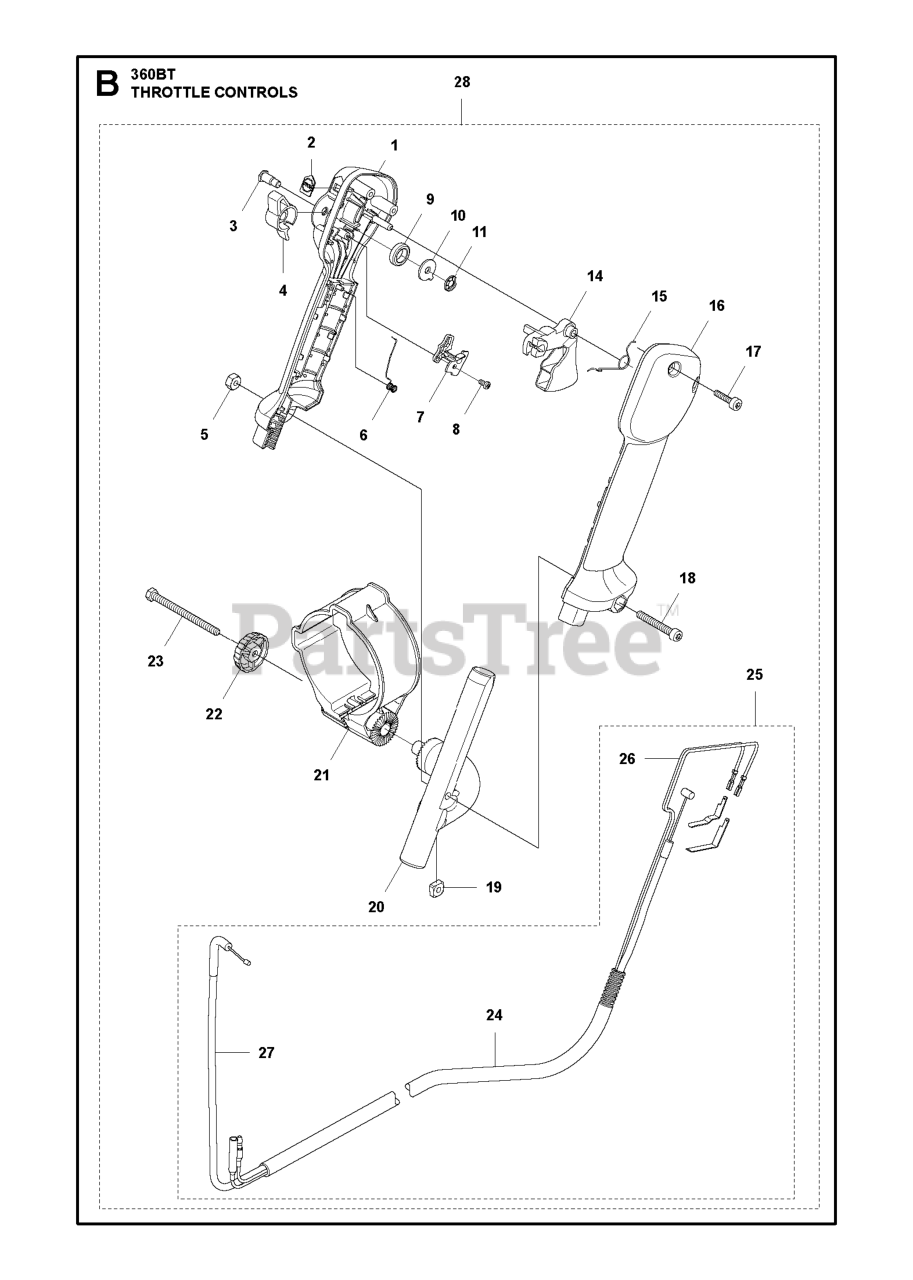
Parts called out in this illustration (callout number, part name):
1	HANDLE HALF (L)
3	SHAFT PIVOT
4	LEVER STOP
9	SPRING RUBBER
12	CONTACT SPRING
13	CONTACT SPRING
14	TRIGGER 848L5W34C0
16	HANDLE HALF (R)
17	SCREW
19	SQUARE NUT M5
20	HOLDER, HANDLE
21	HANDLE HOLDER
22	KNOB
25	WIRING ASSY
26	CORD COMPLETE
27	CABLE, COMP
28	LEVER SET ASSY
